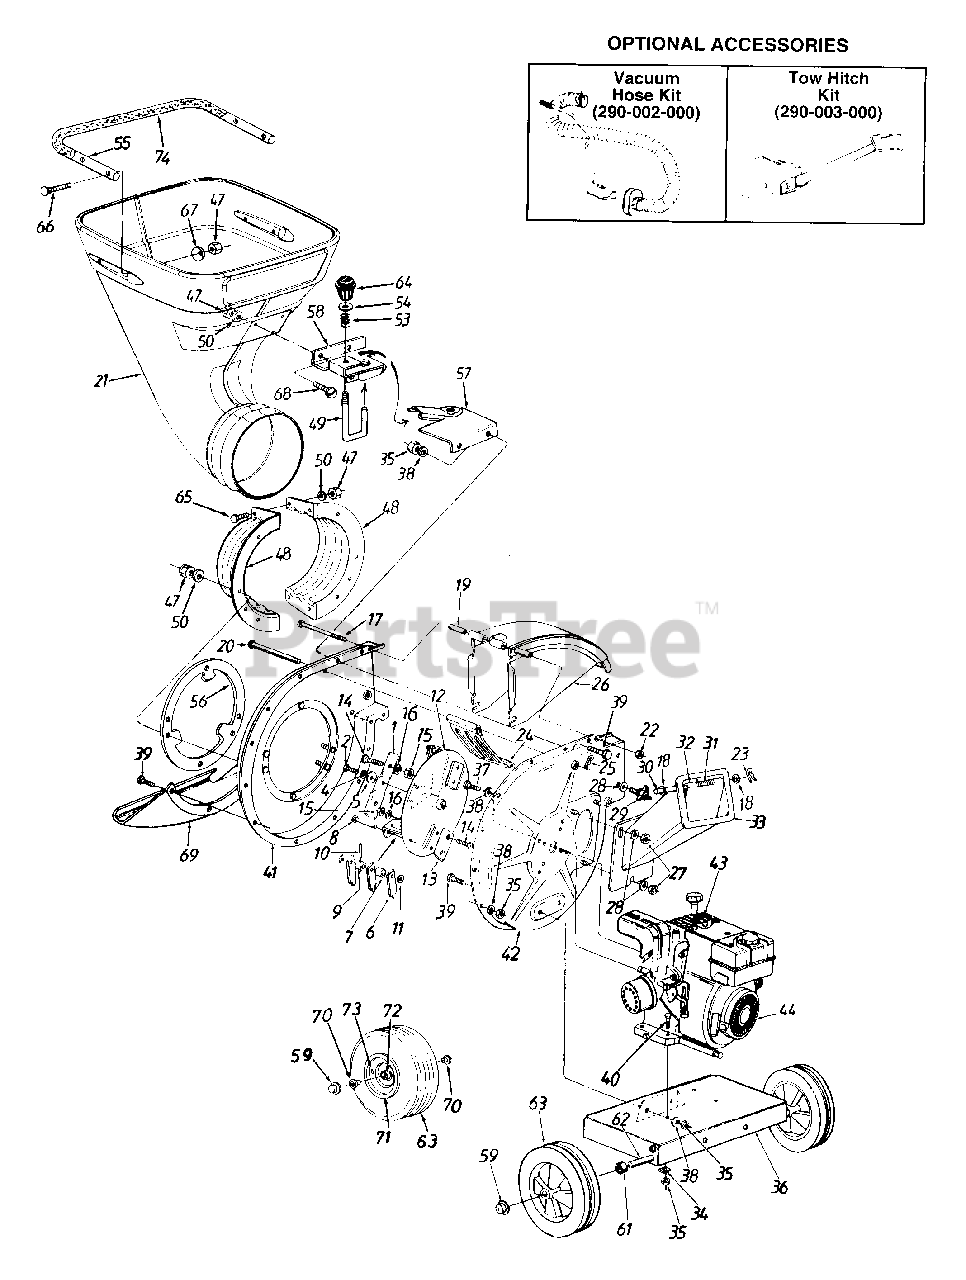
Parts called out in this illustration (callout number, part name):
1	Blade
2	Hex Patch Bolt 3/8-24 x 2.25" Lg.
4	L-Wash. 3/8" I.D. H.D.
5	Fl-Wash. .406" I.D. x 1.25" O.D. Hdn.
6	Flail
7	Flail Spacer
8	Clevis Pin .496" Dia.
9	Flail Spacer w/.160" Dia. Hole
10	Spring Roll Pin 1.12" Lg.
11	Fl-Wash. .531" I.D. x .94" O.D.
12	Impeller Ass'y. Comp.
13	Chipper Blade
14	Flat Hd. Scr. 5/16-24 x .75" Lg.
15	Hex Top L-Nut 5/16-24 (Gr. 5)
16	L-Wash. 5/16" I.D.
17	Hex Bolt 1/4-20 x 3.75" Lg.
18	Fl-Wash. .281" I.D. x .50" O.D.
19	Chute Hinge Spacer 1.66" Lg.
20	Clevis Pin .5" Dia. x 4.62" Lg.
21	Rotating Hopper
22	Hex Ctr. L-Nut 1/4-20 Thd.
23	Cotter Pin
25	Internal Cotter Pin 3/8" Dia.
27	Hex Nut 5/16-18 Thd. (Gr. 5)
28	Bell-Wash. .345" I.D. x .88"
29	Hand Knob
30	Chipper Door Rod
31	Torsion Spring 1.14" Lg.
35	Hex Nut 5/16-18 Thd. (Gr. 5)
37	Hex Bolt 5/16-24 x .75" Lg.
38	L-Wash. 5/16" I.D.
39	Hex Bolt 5/16-18 x .75" Lg. (Gr. 5)
40	Hex Bolt 5/16-18 x 1.5" Lg.
44	Engine
47	Elastic Lock Nut 5/16-18 Thd.
48	Hopper Mtg. Collar
49	Locking Pin
50	Fl-Wash. 5/16" I.D.
53	Spring 1.5" Lg.
54	Fl-Wash. .385" I.D. x .62" O.D.
61	Spacer .64" I.D. x .38" Lg.
62	Shredder Axle
63	Wheel Ass'y. Comp.
64	Knob
65	Hex Bolt 5/16-18 x 1" Lg. (Gr. 5)
66	Curved Carr. Bolt 5/16-18 x 1.25" Lg.
67	Saddle Wash. .32" I.D.
68	Carr. Bolt 5/16-18 x .75" Lg.
70	Flange Bearing .632" I.D.
73	Air Valve
74	Foam Grip
